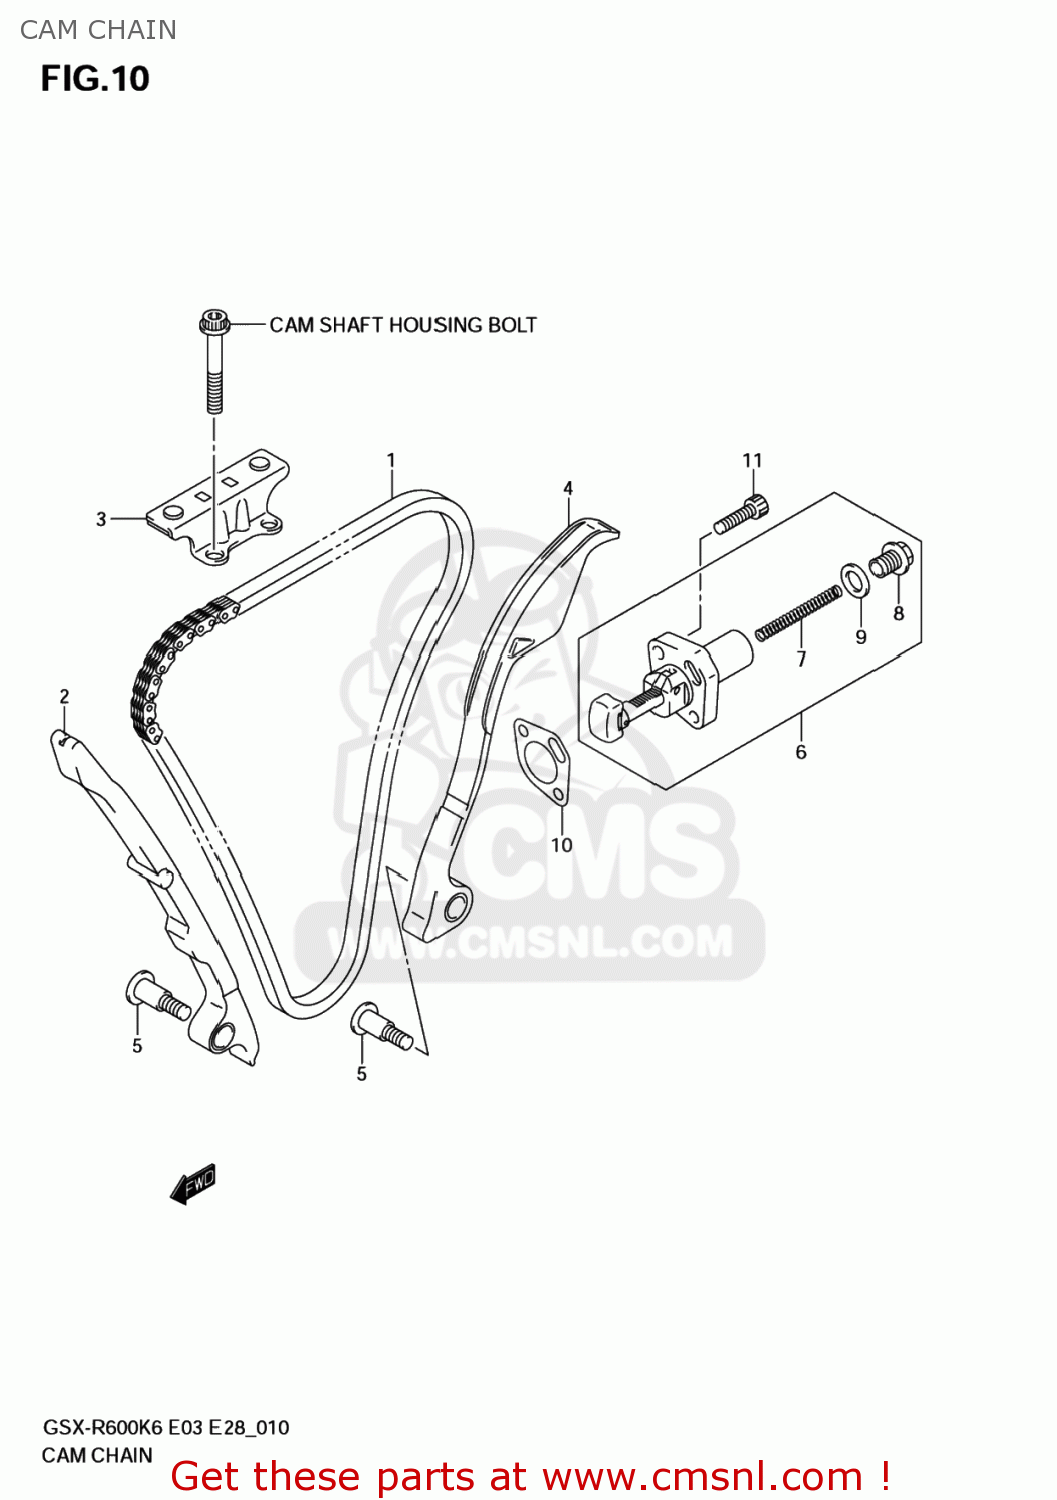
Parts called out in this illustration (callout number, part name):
1	CHAIN,CAMSHAFT DRIVE
2	GUIDE,CAM CHAIN NO.1
3	GUIDE,CAM CHAIN NO.2
4	TENSIONER,CAM CHAIN
5	BOLT,CAM CHAIN TNSN & GUIDE
6	ADJUSTER ASSY,TENSIONER
7	SPRING
8	PLUG,FR TENSIONER ADJ
9	GASKET,TENSIONER ADJUSTER (NAS)
10	GASKET,TENSIONER ADJUSTER (NAS)
11	BOLT
